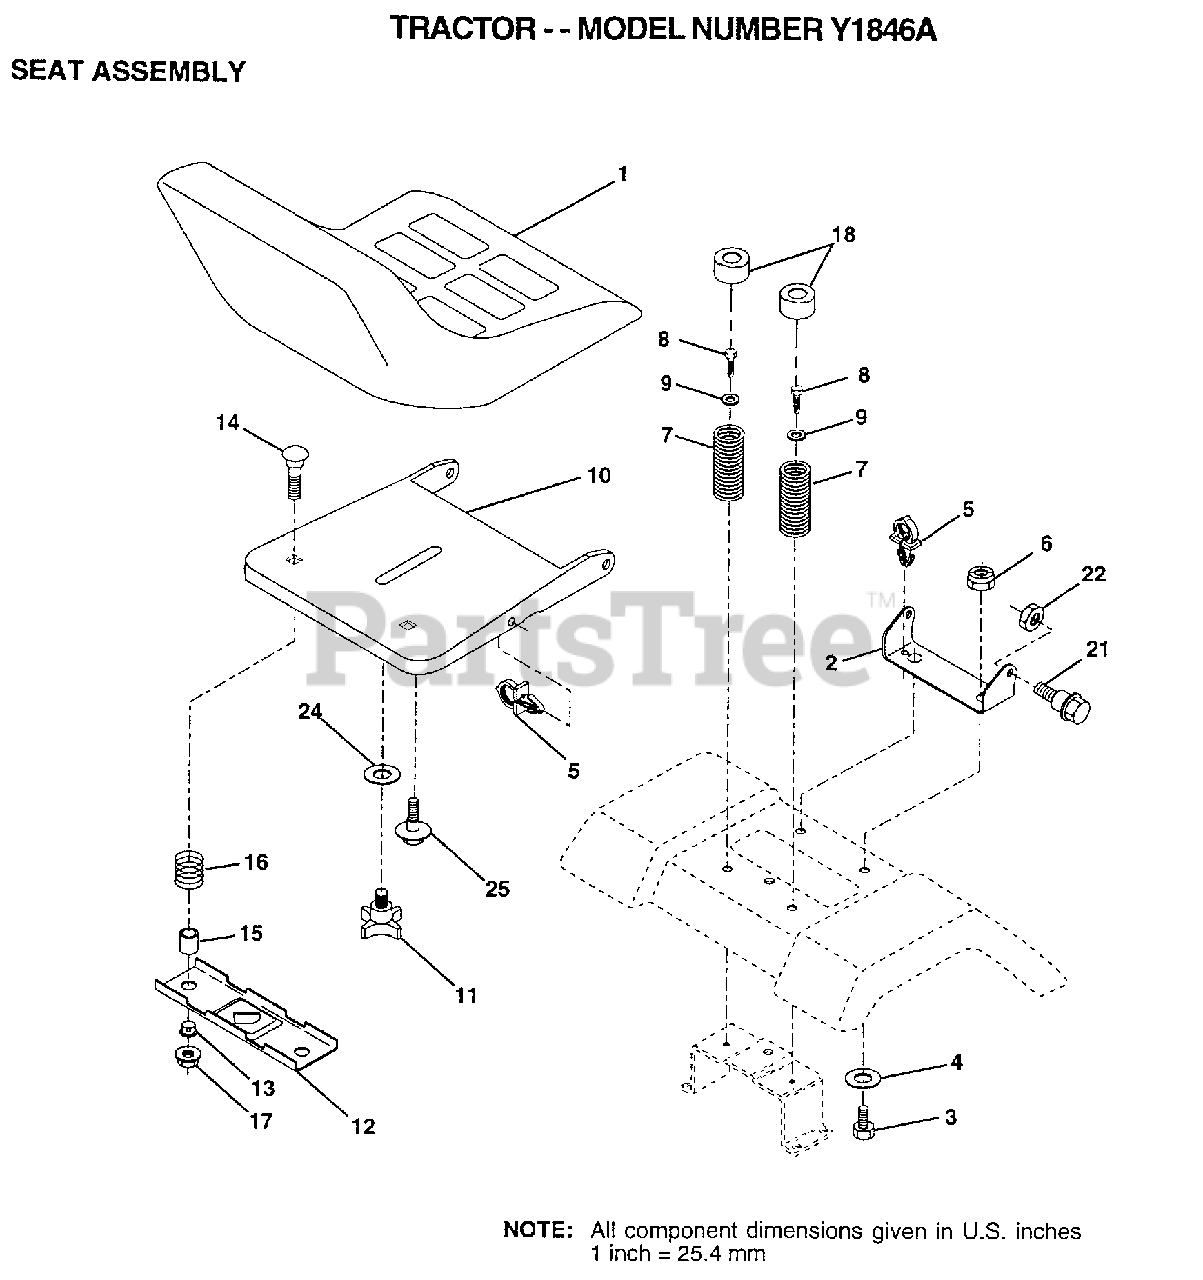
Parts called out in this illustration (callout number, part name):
1	PULLEY
6	BOLT
7	"STRAP,TORQUE"
8	SCREW
9	SPRING.BRAKE.RETU
10	WASHER
11	SQUARE KEY
12	BOLT
16	"SUPT,HDLE SHT LH"
17	"LINK,SHIFT"
18	BOLT.1/4-28.W/PAT
19	LOCKWASHER
20	WASHER LT
21	ARM SHIFT
22	WASH-SHFT PLT LT
23	KNOB T (1/2-HOLE)
24	"ROD,SHIFT"
25	PIN COTTER 1/8
26	NUT.LOCK.5/16-24
28	"SPRING,EXT"
29	"SUPT,HDLE RH"
31	SPACER LT
35	E-RING LT
36	SCREW
